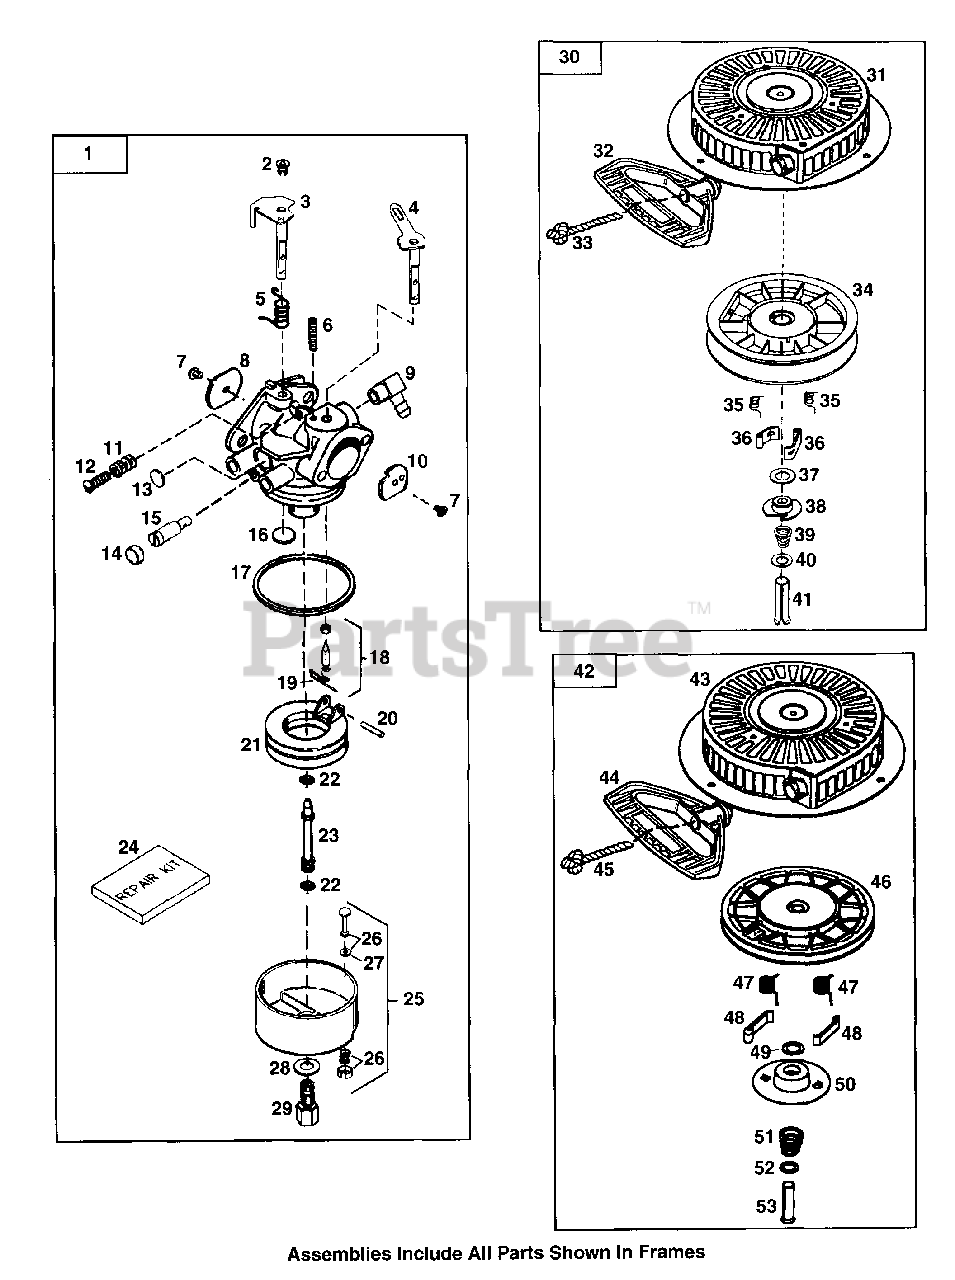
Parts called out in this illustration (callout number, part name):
1	Carburetor Assembly
2	Throttle Link Bushing
3	Throttle Shaft & Lever Assembly
4	Choke Shaft & Lever Assembly
5	Throttle Return Spring
6	Choke Positioning Spring
7	Shutter Screw
8	Throttle Shutter
9	Fuel Fitting
10	Choke Shutter
11	Tension Spring
12	Throttle Crack Screw/Idle Speed Screw
13	Welch Plug, Idle Mixture Well
14	Idle Restrictor Screw Cap
15	Idle Restrictor Screw
16	Welch Plug, Atmospheric Vent
17	Float Bowl O-Ring
18	Inlet Needle, Seat & Clip
19	Spring Clip
20	Float Shaft
21	Float
22	O-Ring, Main Nozzle Tube
23	Main Nozzle Tube
24	Repair kit
25	Float Bowl Assembly
26	Bowl Drain Assembly
27	Drain Plunger Gasket
28	Bowl Nut Washer
29	High Speed Bowl Nut
30	Rewind Starter
31	Starter Housing Assembly
32	Mitten Grip Handle
33	Starter Rope (Length 98" x 9/64" dia.)
34	Pulley & Rewind Spring Assembly
35	Dog Spring
36	Starter Dog
39	Brake Spring
41	Spring Pin
42	Rewind Starter Ass'y
43	Starter Housing Ass'y
44	Mitten Grip Starter Handle
45	Starter Rope (98")
46	Pulley & Rewind Spring Ass'y
47	Dog Spring
48	Starter Dog
51	Brake Spring
53	Spring Pin,
